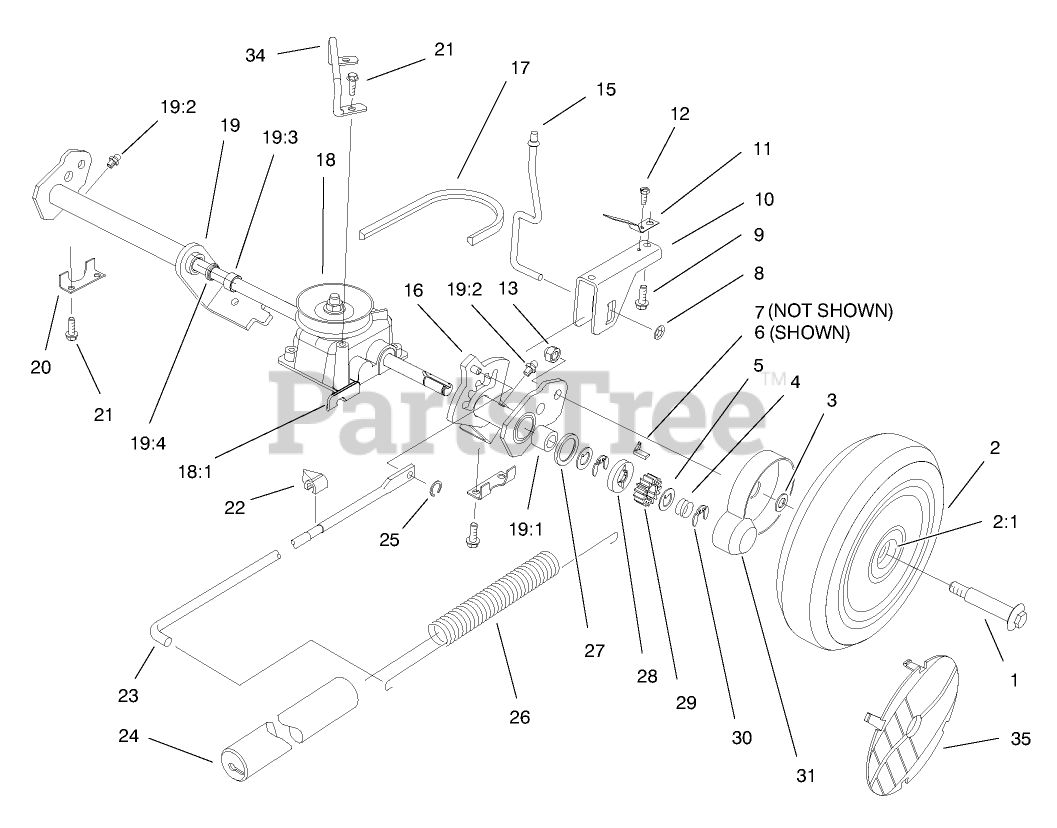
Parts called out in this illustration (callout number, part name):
1	BOLT-WHEEL
2	WHL & TIRE ASSEMBLY
2:1	BUSHING
3	SPACER-COVER, WHEEL
4	SPRING-COMPRESSION
5	WASHER-THRUST, KEYED
6	KEY-ROCKING, LH
7	KEY-ROCKING, RH
8	PUSHNUT
9	SCREW
10	SADDLE - HOC
11	SPRING - TRIGGER RET
12	SCREW 8 - 32 X 250
13	NUT-HEX
15	TRIGGER ROD
16	ASM - LH PIVOT ARM
17	V-BELT
18	GEAR CASE ASSY
18:1	TRACTION BRACKET
19	ASM - RH PIVOT ARM
19:1	BEARING-ROLLER
19:2	FITTING-GREASE
19:3	BUSHING
19:4	SEAL-OIL
20	REAR SECURING PLATE
21	SCREW-HWH
22	INDICATOR-HEIGHT OF CUT
23	LINK ROD
24	COVER-SPRING
25	GRIP RING
26	SPRING-COUNTERBALANCE
27	RING-FRICTION
28	WASHER-CLUTCH
29	GEAR-PINION
30	RING-CLIP, LOCKING
31	COVER-WHEEL
34	Retainer Belt
35	COVER-WHEEL
